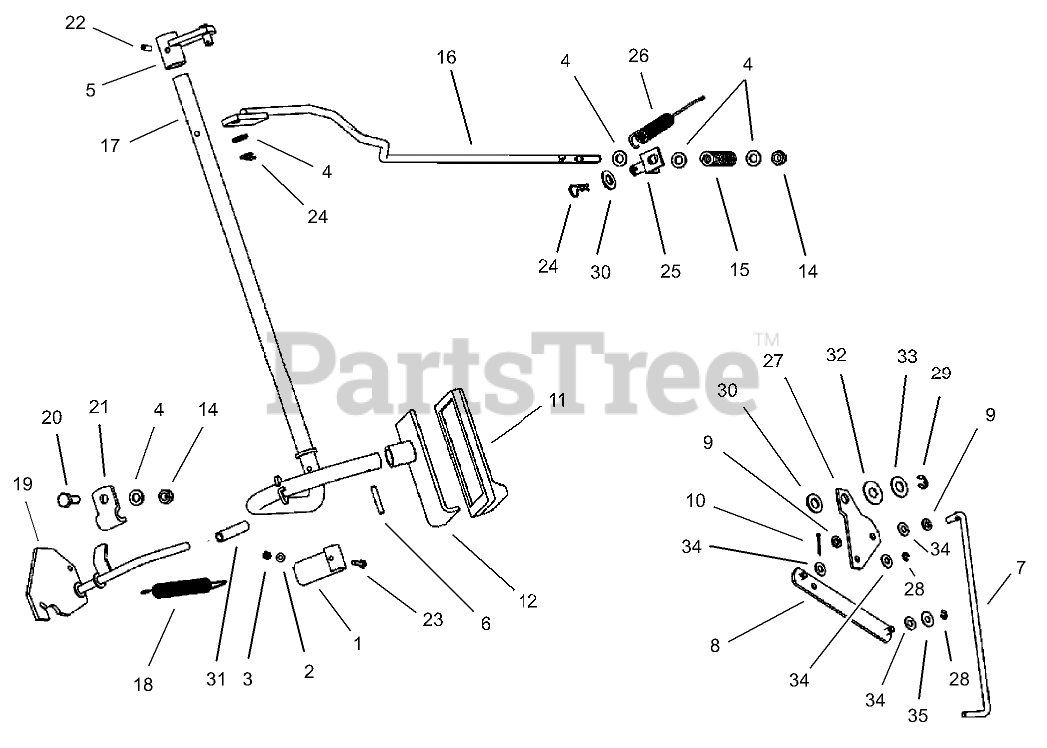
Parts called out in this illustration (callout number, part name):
1	LEVER-SPRING
2	WASHER
3	NUT-HEX
4	WASHER-PLAIN
5	BRACKET-ROD, BRAKE
6	PIN-SPRING
7	ROD-LEVER, BYPASS
8	Lever-Bypass
9	WASHER
10	PIN-COTTER
11	PAD-PEDAL
14	NUT-LOCK, NI
15	SPRING-BRAKE
16	ROD-CONNECTING, BRAKE
17	Shaft-Brake
18	SPRING-BRAKE, HAND
19	LEVER-BRAKE, HAND
20	SCREW-HH
21	CLAMP-LEVER, PARKING BRAKE
22	PIN-SPRING
23	SCREW-HEX
24	PIN-COTTER
25	BRACKET-ROD, BRAKE
26	SPRING
27	Plate-Bypass
28	STIRRUP
29	E-CLIP
30	WASHER-FLAT
32	Washer
33	Washer
34	Washer
35	Washer
